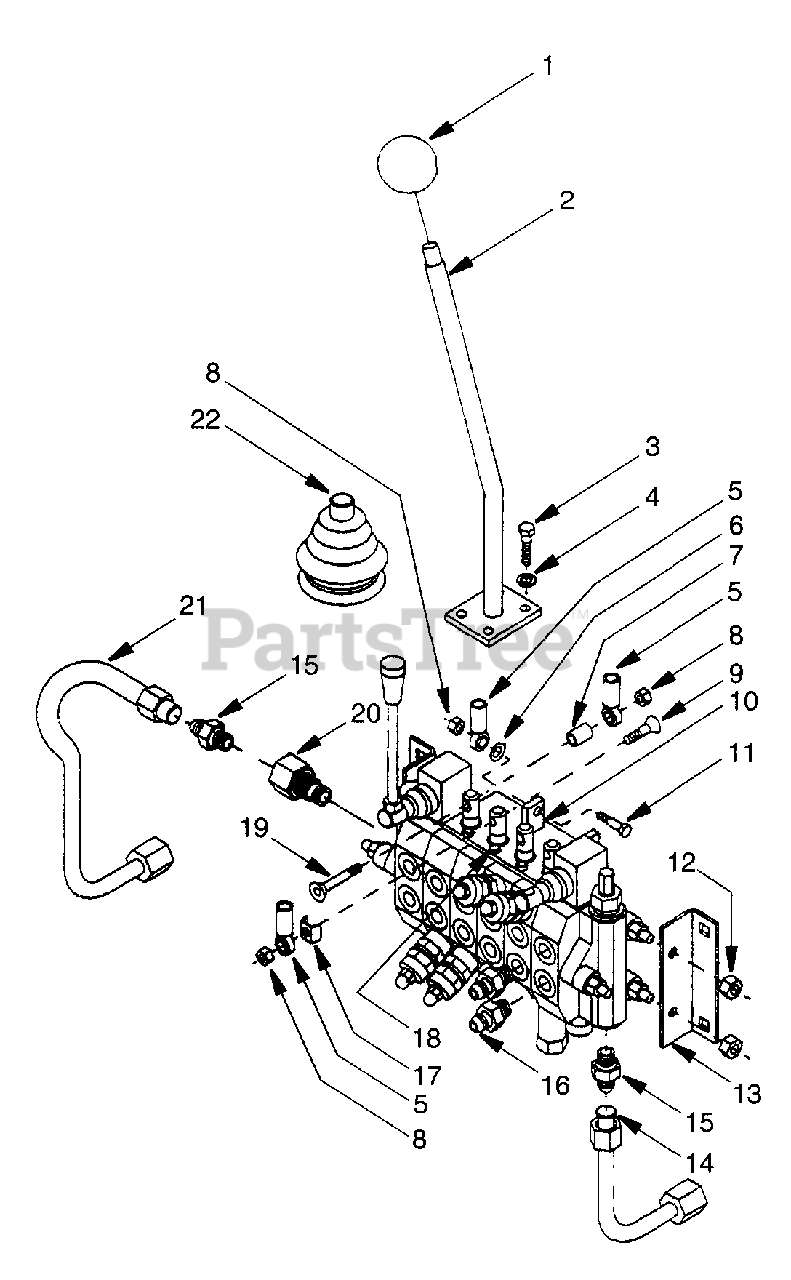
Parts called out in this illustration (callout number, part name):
1	Knob, 1.88 Dia. x 1/2 NC
2	Control Handle
3	Hex Hd Cap Screw, 5/16 NF x 3/4 GR5
4	Lockwasher, 5/16
5	Female Rod End, 5/16 NF
6	Washer, .328 x .50 x .093
7	Sleeve, .328 x .463 x .716
8	Hex Locknut, 5/16 NC
9	Countersunk Hd Screw, 5/16 NC x 1.5
10	Valve Linkage Mount
11	Hex Hd Cap Screw, 5/16 NC x 1.25 GR5
12	Hex Nut, 8mm x 1.25P
13	Valve Mounting Bracket
14	Hyd Tube Assembly, JIC 8F x SAE 8F
15	Adapter, JIC 8M x O-Ring 8M
16	Connector, 9/16-18 to O-Ring
17	Clip, 16GA x .36 x .67 x .63
18	Hex Hd Cap Screw, 5mm x.8P x 12mm
19	Countersunk Hd Screw, 5/16 x 2
20	Power-Beyond Sleeve
21	Hyd Tube Assy, 3/4 SAEF JIC8F
22	Rubber Control Boot
